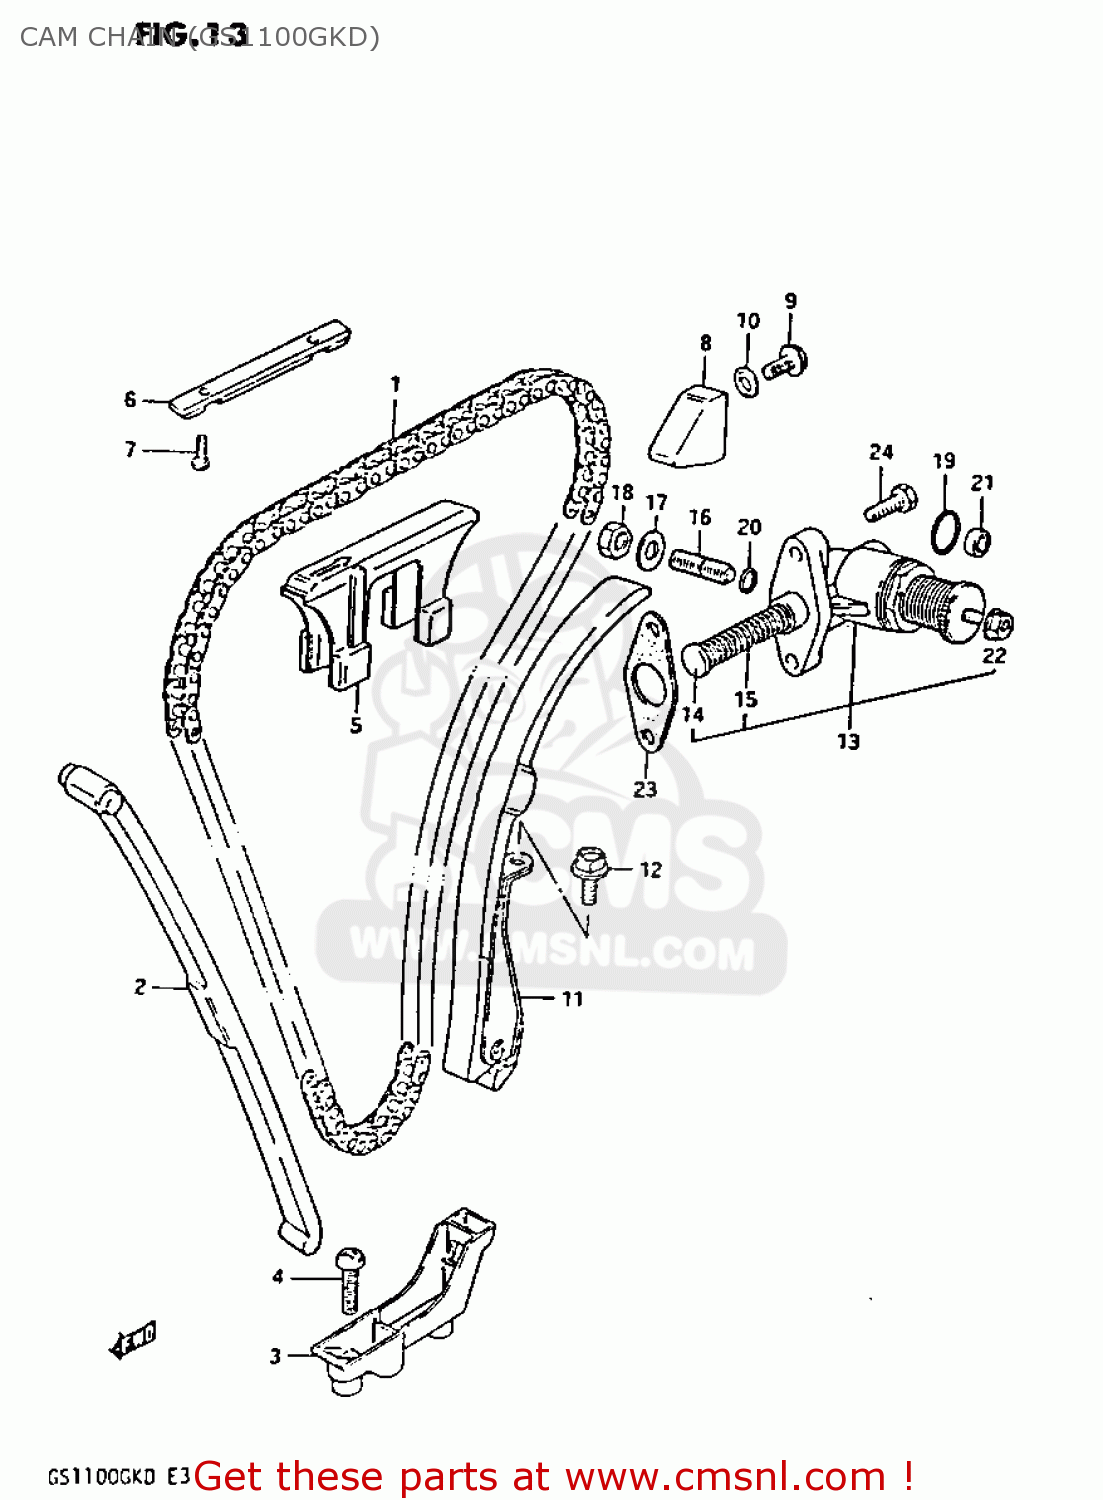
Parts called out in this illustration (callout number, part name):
1	CHAIN,CAMSHAFT DRIVE
2	GUIDE,CAM CHAIN NO.1
3	HOLDER,CAM CHAIN GUIDE
4	SCREW
5	GUIDE,CAM CHAIN NO.2
6	GUIDE,CAM CHAIN
7	SCREW
8	GUIDE,CAM CHAIN
9	BOLT 6X12
10	GASKET(5.8X13X1.2) (NAS)
11	TENSIONER,CAM CHAIN
12	BOLT 8X16
13	ADJUSTER ASSEMBLY,TENSIONER
14	ROD,PUSH
15	SPRING
16	SCREW,TENSIONER ADJUST
17	WASHER
18	NUT
19	O RING(D:2.4,ID:20.8)
20	O RING(D:1.9,ID:5.7)
21	SEAL,OIL(10X16X4)
22	NUT 6MM
23	GASKET,TENSIONER ADJUSTER (MCA)
24	SCREW
